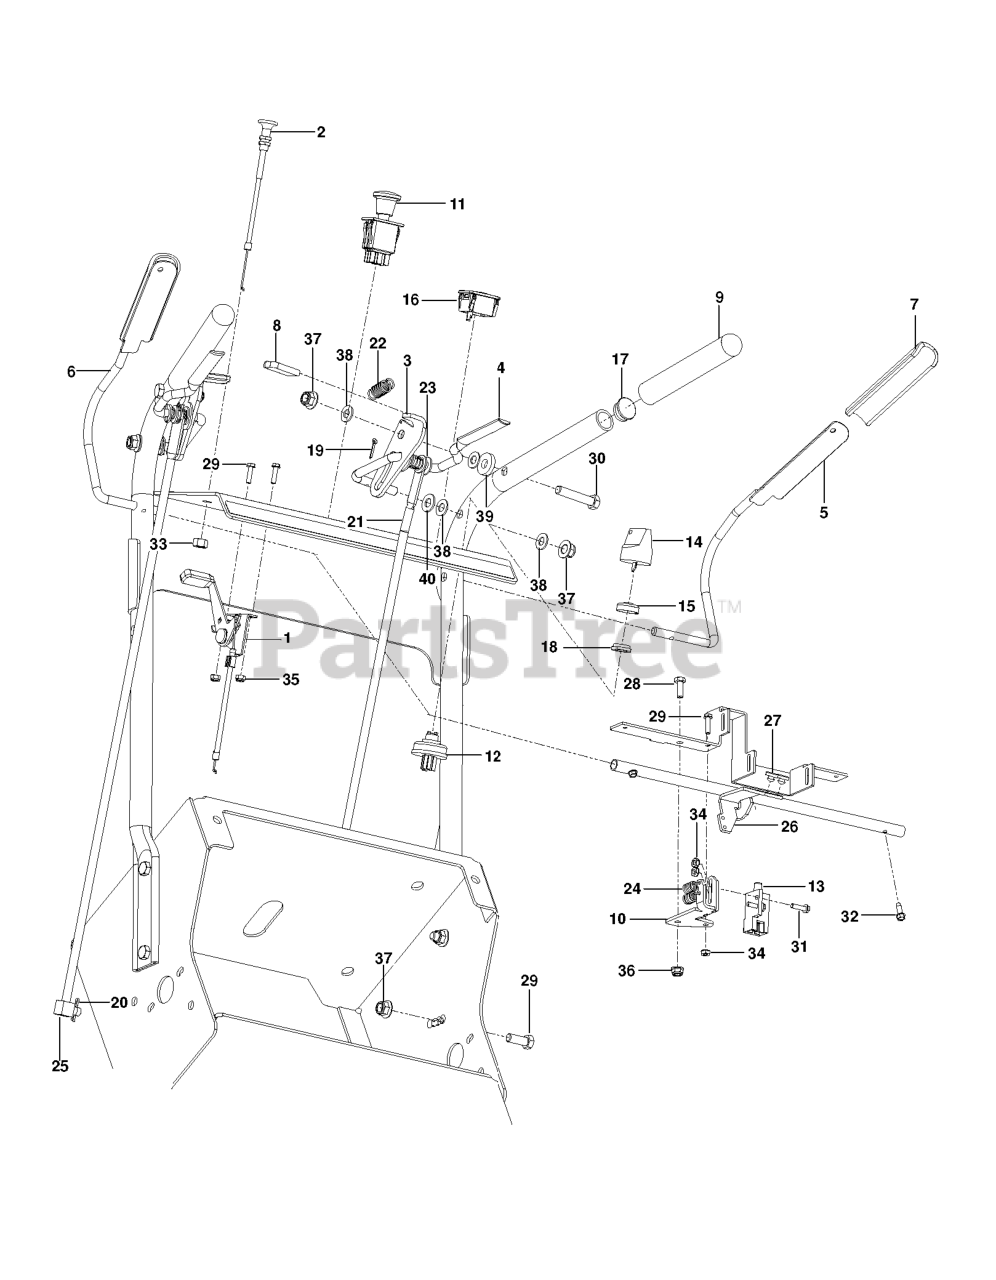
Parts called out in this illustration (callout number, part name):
1	CABLE CABLE - THROTTLE W/LINER
2	CABLE CABLE, CHOKE
3	LATCH LATCH, RH THUMB HUSQ
3	LATCH LATCH, LH THUMB HUSQ
4	LEVER LEVER, HAND CONTROL RH
4	LEVER LEVER, HAND CONTROL LH
5	LEVER LEVER RH OP MY14 HUSQ
6	LEVER LEVER LH OP MY14 HUSQ
7	GRIP GRIP, CLUTCH LEVER, LH AN
8	GRIP GRIP, THUMB LATCH
9	GRIP GRIP, HANDLEBAR
10	SWITCH SWITCH & SPRING HUSQ
11	SWITCH SWITCH, CLUTCH
12	KEY KEY SWITCH INDAK #3S463A
13	SWITCH SWITCH,INTERLOCK
14	KEY KEY W/ SHIELD
15	CAP CAP - IGNITION SWITCH
16	METER METER, HOUR INDCTV RECOI
17	CAP CAPLUG, HANDLEBAR
18	NUT NUT, PANEL .562-24 GRECO
19	PIN PIN-CTR .09 X .75 E X TPRS
20	PIN PIN-HAIR, ENDRIES #25 YWZC
21	ROD ROD, STEERING
22	SPRING SG-TENS .041 X .500 X 1
23	SPRING SG-COMP .045 X .600 X .
24	SPRING SG-TENS .047 X .438 X 1
25	SWIVEL SWIVEL, 3/8-24
26	TUBE PIVOT TUBE HUSQ
27	BUMPER BUMPER GROMMET .125 X .
28	BOLT BOLT HEX .25-20X.75 GR5 Y
29	BOLT BOLT HEX .38-16 X 1.00 GR
30	BOLT BOLT HEX .38-16 X 2.00 GR
31	SCREW SCREW, MCH 10-24 X .75 H
32	SCREW SCREW, TAP 12-24 X .625
33	NUT NUT, HEX .375-24 YWZC GR2
34	NUT NUT, 10-24 KEPS
35	NUT NUT, LK-NYL 10-24 W/INSRT
36	NUT NUT, LK-NYL-FLG .25-20 YWZ
38	WASHER WASHER, FL-NY .375 X .7
39	WASHER WASHER, FL-STL .406 X 1
